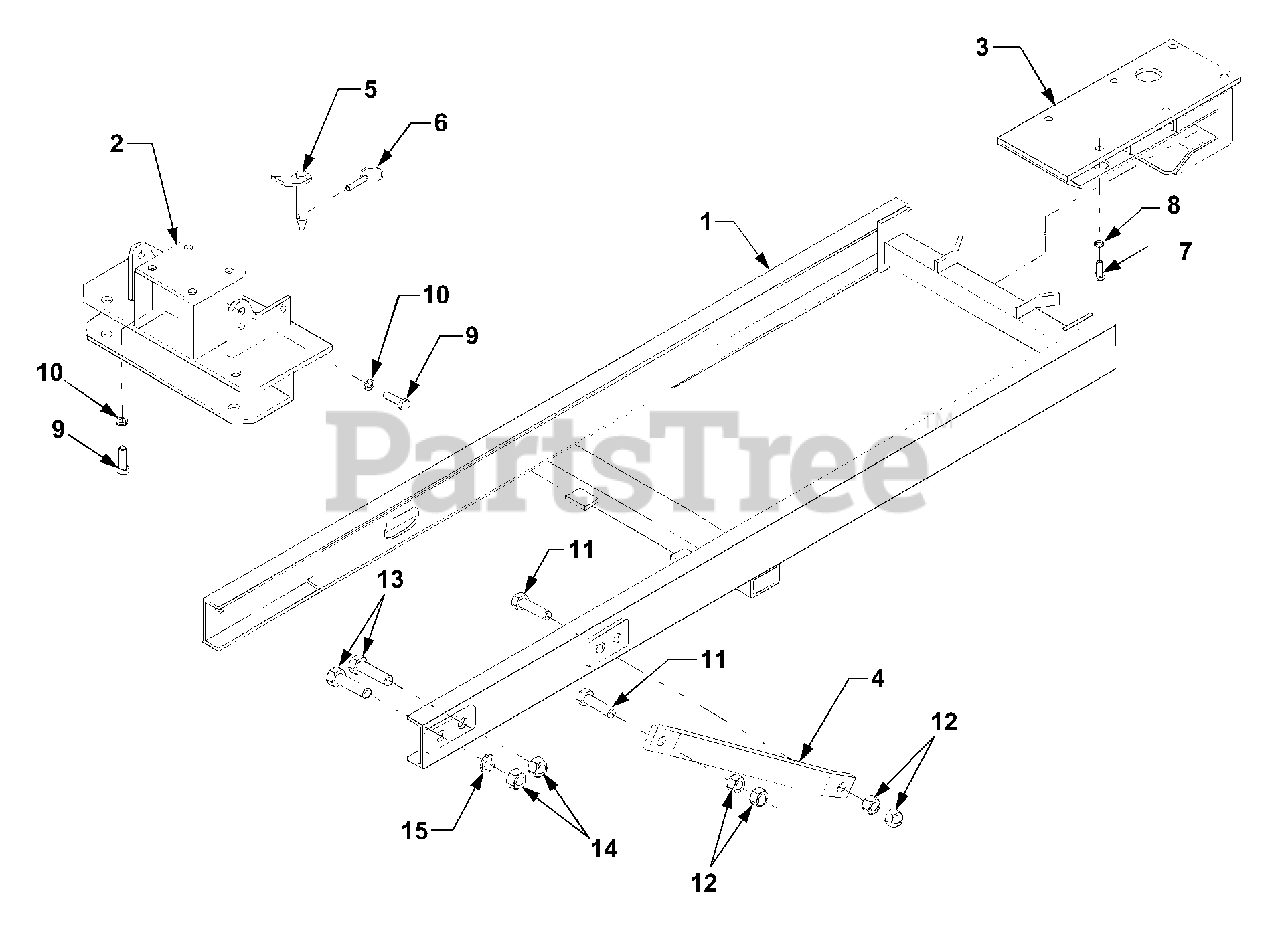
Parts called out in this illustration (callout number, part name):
2	Rear Subframe Mount
3	Front Subframe Mount
5	Retaining Pin
7	Hex Head Screw, M12 x 1.2
8	Spring Washer
9	Hex Head Screw, M14 x 45
10	Spring Washer
11	Hex Head Screw, M20 x 2.5
12	Hex Nut, M20
13	Hex Head Screw, M22 x 2.5
14	Hex Nut, M22
15	Spring Washer M22
16	Spring Washer M20
